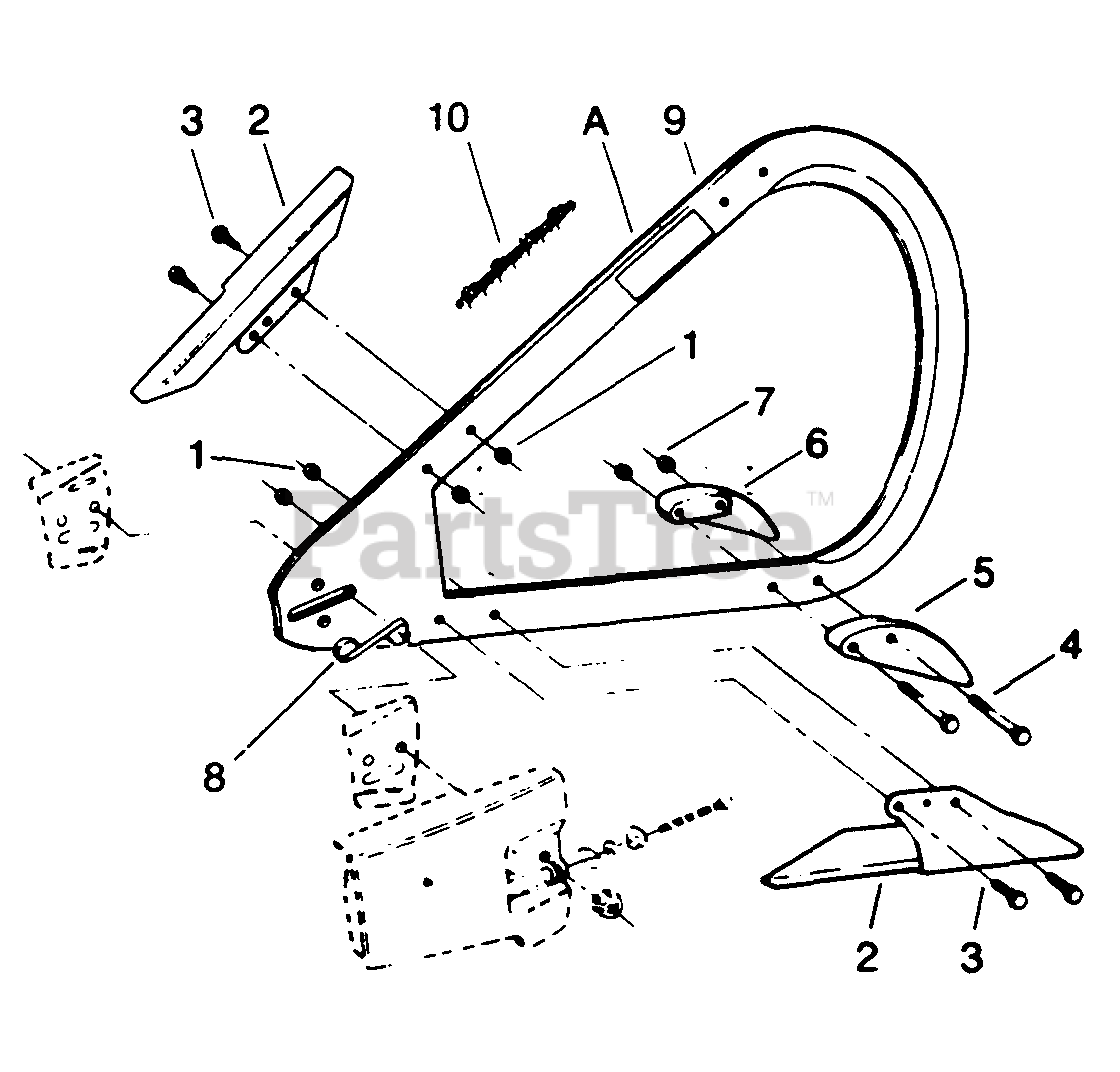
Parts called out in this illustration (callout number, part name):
1	Locknut - (12 - 24)
2	Chain Guard - Upper and Lower
3	Screw - Guard Mtg. (12 - 24 x 5/8 - Hex Hd.)
4	Screw - Spike Mtg.(1/4 - 20 x 1-3/4 - Hex Hd.)
5	Bumper Spike - Right
6	Bumper Spike - Left
7	Locknut - Bumper Spike Mounting (1/4 - 20)
8	"S" Clip
9	Bow Guide
10	Chain
10	13" Reversible Bow Attachment
10	14" Reversible Bow Attachment
A	Decal - Bow Guide Warning
